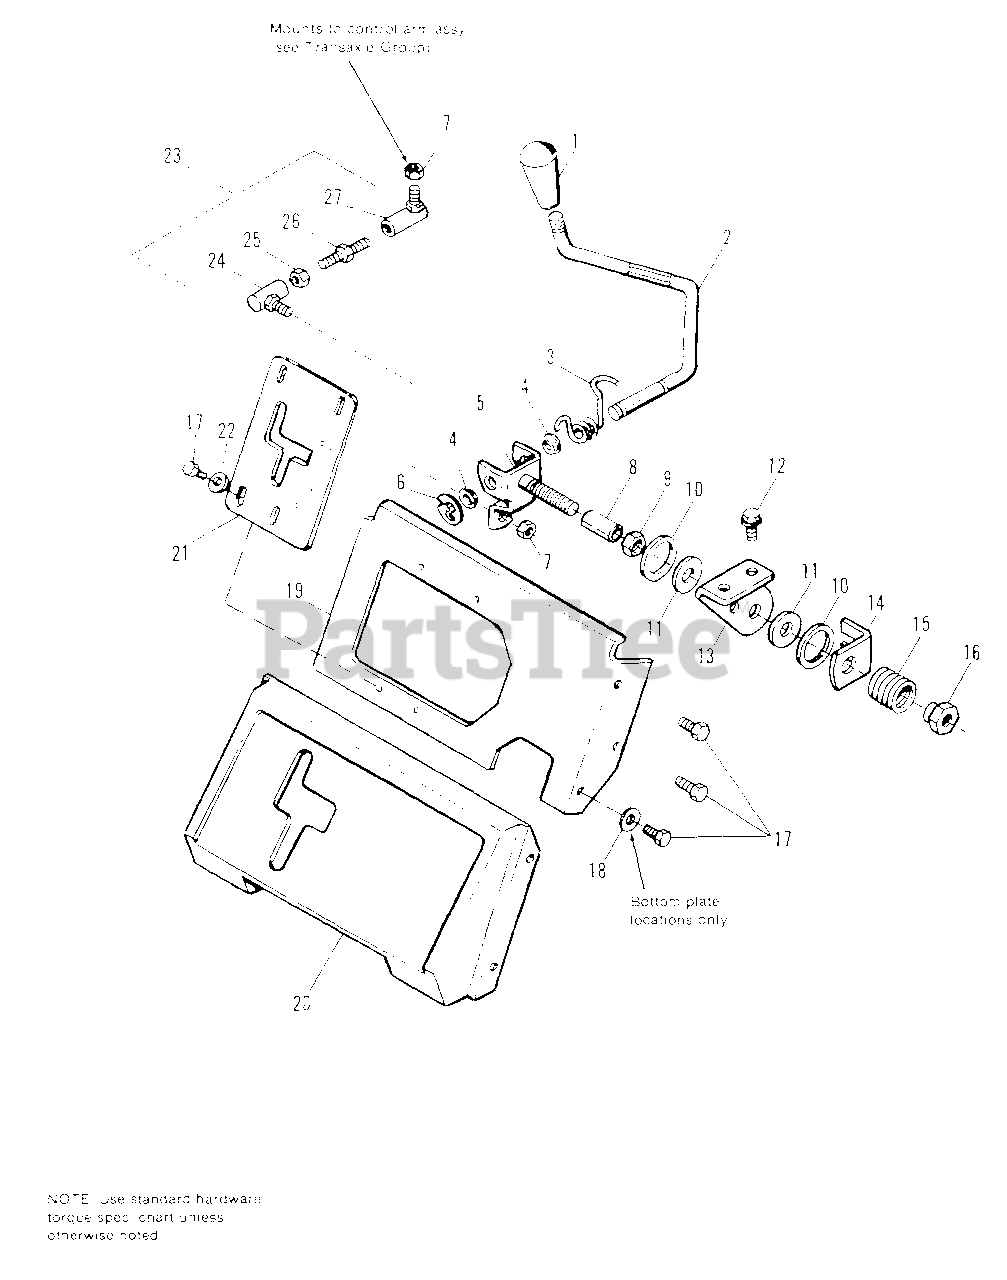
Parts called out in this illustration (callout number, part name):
1	HANDLE, Speed Control
3	SPRING, Torsion
5	BRACKET ASSY., Speed Control
6	E-RING
7	NUT, Centerlock, 3/8-24
9	NUT, Hex Lock, 3/8-16
10	RING, Containment
11	DISC, Friction
12	SCREW, Taptite, 5/16-18 x 5/8
13	BRACKET, Speed Control Support
14	BRACKET, Pivot
15	SPRING, Compression
16	NUT, Spacer
17	SCREW, Taptite, 1/4-20 x 1/2
18	WASHER, 1/4
19	PLATE, Quadrant Mounting
20	PANEL, Shift
21	QUADRANT, Speed Control
22	WASHER, 1/4
23	BALL JOINT ASSY., (Incl. Ref. Nos. 24-27)
24	BALL JOINT, R.H. Thrd.
25	JAM NUT, 3/8-24
26	ADJUSTER ROD
27	BALL JOINT, L.H. Thrd.
